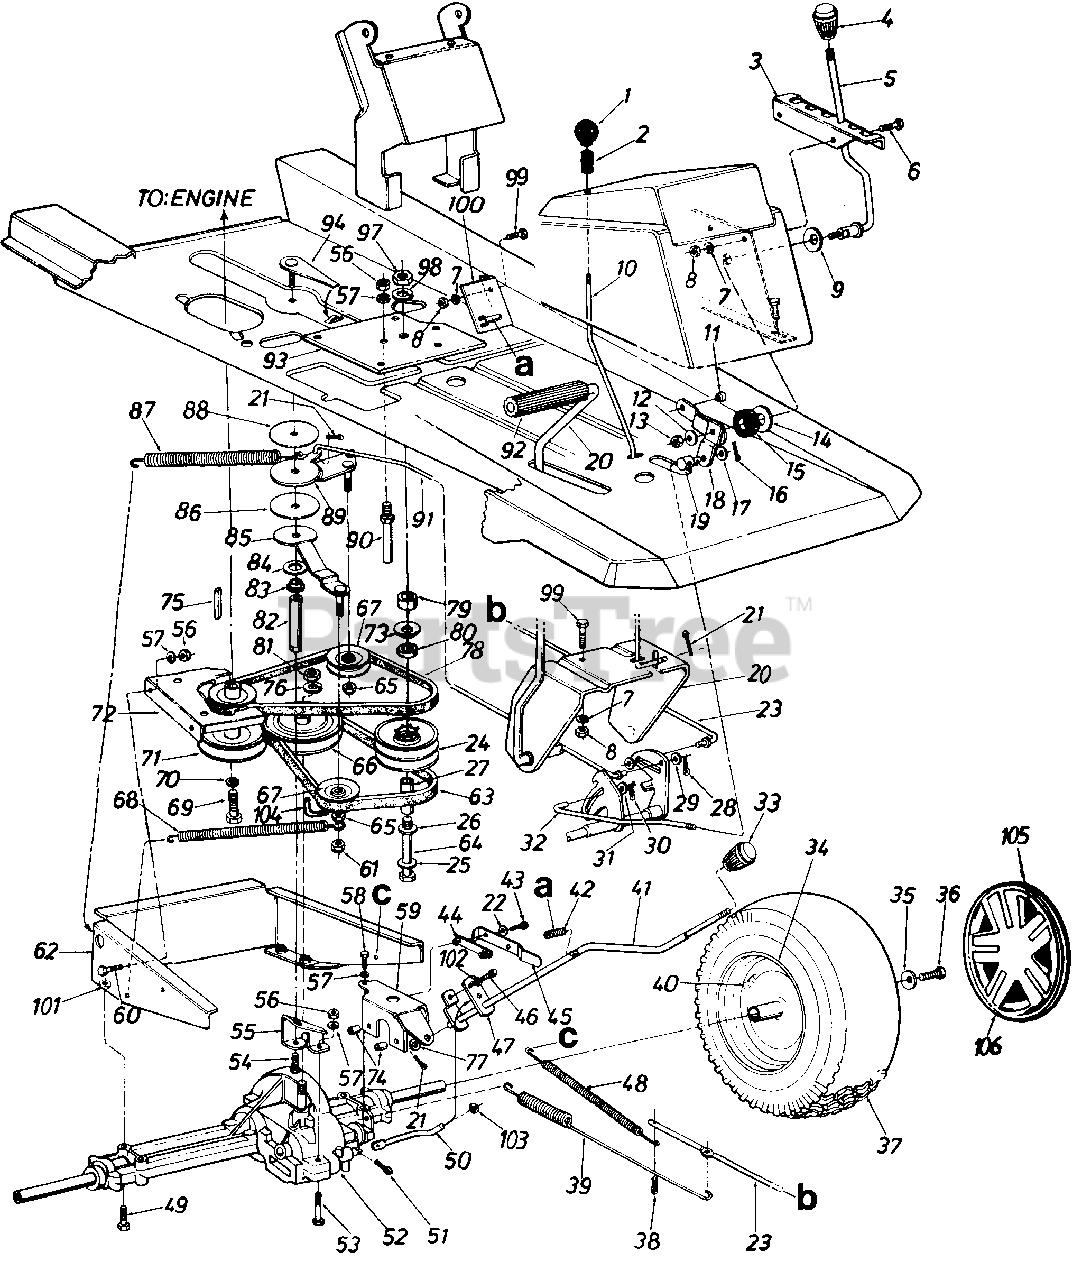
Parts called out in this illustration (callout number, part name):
1	Ball Knob 1/4-20 Thd. 1.25"
2	Compression Spring
5	Speed Control Lever
6	Truss Mach. Scr. 5/16-18 x .75" Lg.
7	L-Wash. 5/16" l.D.
8	Hex Nut 5/16-18 Thd.
9	Bell-Wash. .345" I.D. x .88"
10	Brake Locking Rod
12	Bell-Wash. .345" I.D. x .08"
13	Hex Cent. L-Nut 5/16-18 Thd.
14	Fl-Wash. .50" l.D. x 1.5" O.D.
15	Rubber Washer
16	Intern. Cotter Pin 1/2" Dia.
17	Fl-Wash. .34" l.D. x.68" O.D.
18	Speed Control Lever Brkt. Ass'y.
19	Ferrule-Engagement
20	Clutch/Brake Pedal Ass'y.
21	Cotter Pin 3/32" Dia. x .75"
22	Plastic Washer
24	Variable Speed Pulley Ass'y.
25	Fl-Wash. .4" l.D. x 1.25" O.D.
26	Thrust Brg. 1.25" O.D. x .56" I .D.
27	Spacer Sleeve 2.71"
28	Cotter Pin 1/8" Dia. x 1.25"
29	Fl-Wash. .34" l.D. x.60" O.D.
30	Intern. Cot-Pin 5/16" Dia.
31	Fl-Wash. .34" l.D. x .60" O.D.
32	Speed Control Rod
33	Shift Knob
35	Bell-Wash. .345" l.D. x .88n
36	Hex L-Bolt 5/16-24 x .75" Lg.
38	Cotter Pin 1/8" Dia. x 1.25"
39	Extension Spring 17.0" Lg.
40	Air Valve
43	Hex Wash. Hd. Scr. #8 x .5" Lg
44	Insulator Nut
45	Spring Switch
46	Hex Bolt 1/4-20 x .50" Lg.
47	Shift Lever Adjusting Link
48	Ext. Spring 81/4" Lg.
49	Hex Bolt 5/16-18 x 2.5" Lg.
51	Intern. Cotter Pin
52	Transaxle
53	Hex Bolt 1/4-20 x 1.75" Lg.
54	Hex Bolt 3/8-24 x 75" Lg.
57	L-Wash. 1/4" I.D.
58	Self-Tap Mach. Scr. Type "C" 1/4-20 x 1.37" Lg.
59	Shift Lever Support Brkt.
60	Hex Bolt 1/4-20 x 1.00" Lg.
61	Hex L-Nut 3/8-24 Thd.
64	Hex Bolt 3/8-16 x 4 5" Lg.
65	Hex Ins. L-Nut 3/8-24 Thd.
66	5/8 V-Pulley 500" l.D. x 6"
67	V-Belt Idler 88" l.D. x 3.06"
68	Ext. Spring 50" O.D. x 6 87n
69	Hex Bolt 7/16-20 x 1.00" Lg.
70	L-Wash. 7/16" l.D.
71	Engine Pulley 500" O.D. & 8.86" O.D.
72	Upper Eng. Belt Guard
73	Bell-Wash. .4" l.D. x 1.12" O.D.
74	Spacer.256" l.D. x 50" O.D.
75	Sq.-Key l/4" x 2 00" Lg.
76	L-Wash. 1/2" l.D.
77	Fl-Wash. 469" l.D. x .88" O.D.
78	V-Belt
79	Spacer 1.00" x .380" O.D.
80	Thrust Wash. 56" l.D. x 1.25" O.D.
81	Hex Nut 1/2-13 Thd.
83	Flange Bearing .378
84	Fl-Wash. .640" l.D. x 1.24"
85	Idler Bracket Ass'y.
86	Thrust Wash. 635" l.D.
87	Extension Spring 7.58" Lg.
88	Thrust Wash. 385" l.D.
89	Idler Bracket Ass'y. For Clutch
90	Belt Guard Pin 1/4" Dia.
92	Foot Pad
93	Mtg. Brkt. Variable Pulley
98	L-Wash. 3/8 Heavy Duty
99	Hex Bolt 5/16-18 x 75" Lg.
100	Shift Lever Spring Brkt.
101	Hex Sems Nut 5/16-18 Thd.
102	Bell-Wash. .265" l.D. x .75" O.D.
103	Push On Retaining Ring
105	Spring Clip
